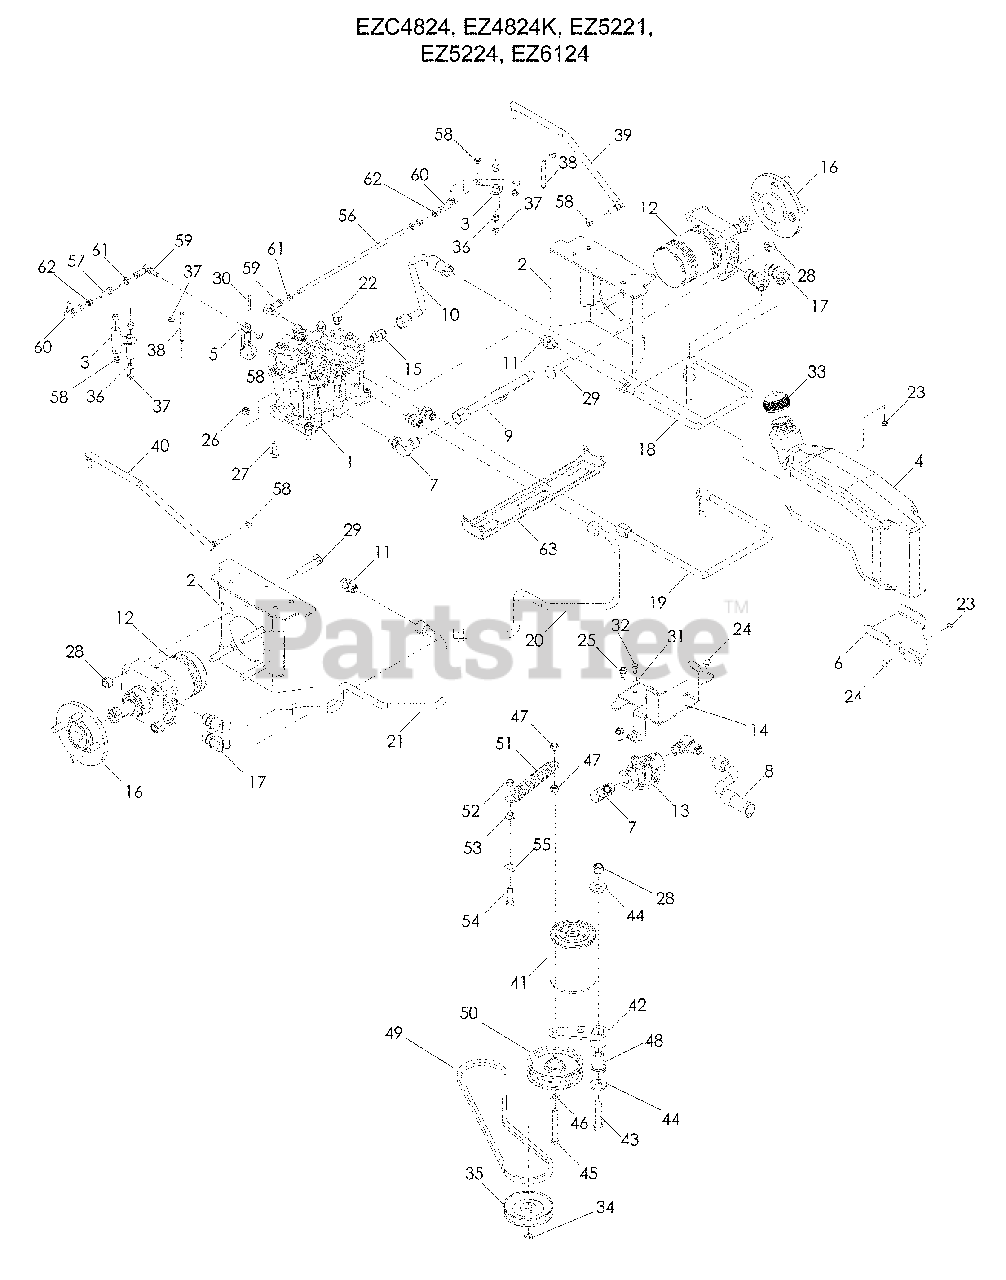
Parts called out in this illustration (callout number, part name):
1	PUMP, DUP10S
2	MOUNT, WHEEL MOTOR
3	BELLCRANK, MOTION
4	RESERVOIR, HYDRAULIC
5	ARM, PUMP
6	SUPPORT, RESERVOIR FT
8	LINE, HYD, SUCTION
9	LINE, HYD, CHARGE
10	LINE, HYD, CASE
11	CONNECTOR, STRAIGHT
13	FILTER HEAD
14	SUPPORT, RESERVOIR RR
15	FITTING, HYD
16	HUB, WHEEL
18	LINE, HYD, D
19	LINE, HYD, C
20	LINE, HYD, B
21	LINE, HYD, A
22	PLUG, 6408-6
23	NUT ¼-20 HEX THIN NYLOC
24	RHSSNB ¼-20 x ½
25	BOLT 5/16-18 x ¾ THD FRM
26	NUT 5/16-18 FLANGE NYLOC
27	RHSNB 5/16-18 x 1¼
28	NUT ½ HEX NYLOC
29	RHSNB ½-13 x 2½
30	PIN, SPIRAL 5/32 x 1½
31	WASHER ¼ SPTLK
32	HCS ¼-20 x 5/8
34	NUT, M10-1.5 L/H HEX
35	PULLEY, PUMP
36	BUSHING, BAIL 5/16
37	RING RETAINING 5/16 EXT
38	PIN, MOTION
39	LINKAGE, CONTROL LT
40	LINKAGE, CONTROL RT
41	FILTER, OIL
42	IDLER ARM WLDMT
43	HCS ½-13 x 2½
44	WASHER ½ FLAT
45	HCS 3/8-16 x 3 TAPBOLT
46	WASHER, 3/8 SAE FLAT
47	NUT 3/8-16 HEX NYLOC
48	PIVOT, IDLER
50	PULLEY, IDLER
51	SPRING, TRACTION
52	NUT 3/8-16 HEX JAM NYLOC
53	NUT 3/8-16 HEX WHIZLK
54	HCS 3/8-16 x 1½ TAPBOLT
55	WASHER 3/8 FLAT STD
56	LINKAGE, CONTROL, RR LT
57	LINKAGE, CONTROL, RR RT
58	NUT 5/16-24 TOP LK
59	SPHERICAL ROD END RH
60	SPHERICAL ROD END LH
61	NUT 5/16-24 HEX JAM LH
62	NUT 5/16-24 HEX JAM
63	SUPPORT, WHEEL MOTOR
